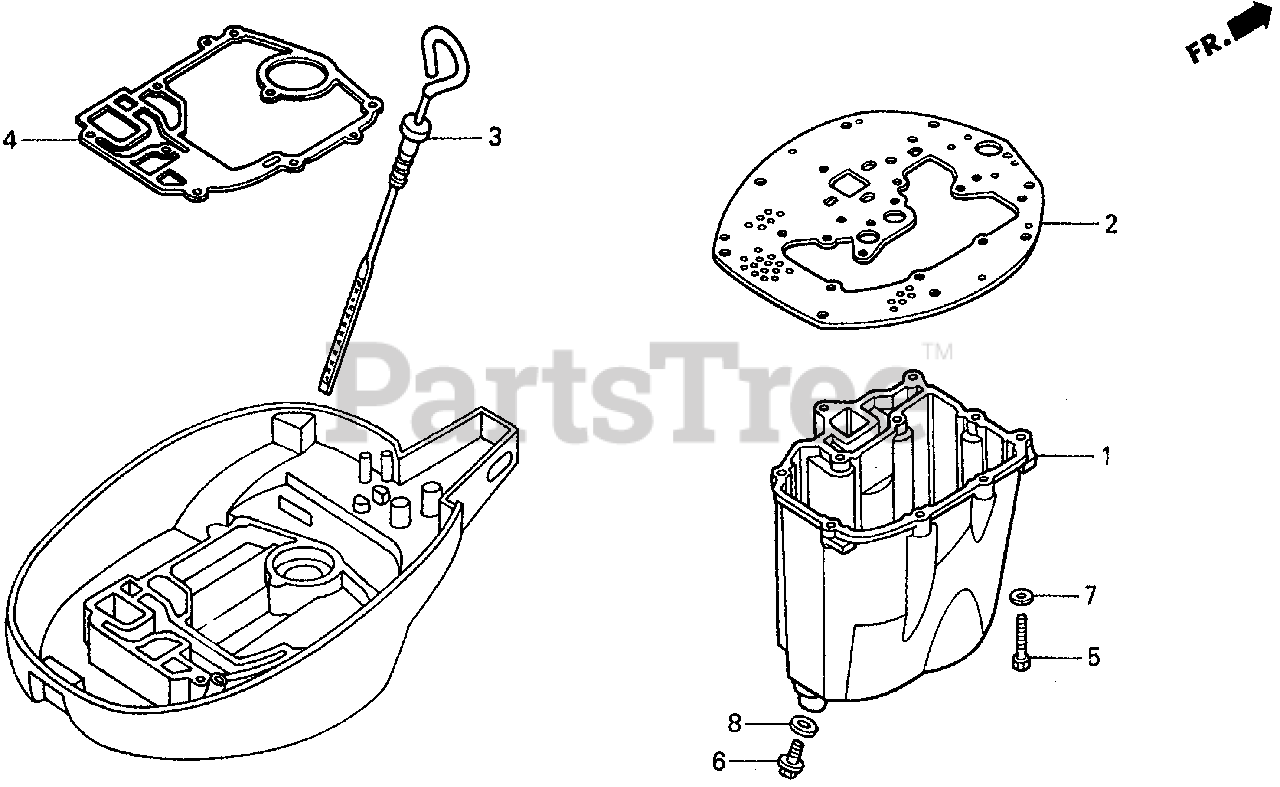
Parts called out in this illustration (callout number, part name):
1	PAN, OIL *TGRAY* (T GRAY)
2	GASKET, OIL PAN
3	DIPSTICK, OIL
4	GASKET, ENGINE CASE (LOWER)
5	BOLT, HEX. (6X25)
6	BOLT, DRAIN PLUG
7	WASHER, PLAIN (6MM)
8	WASHER, DRAIN PLUG (12MM)
